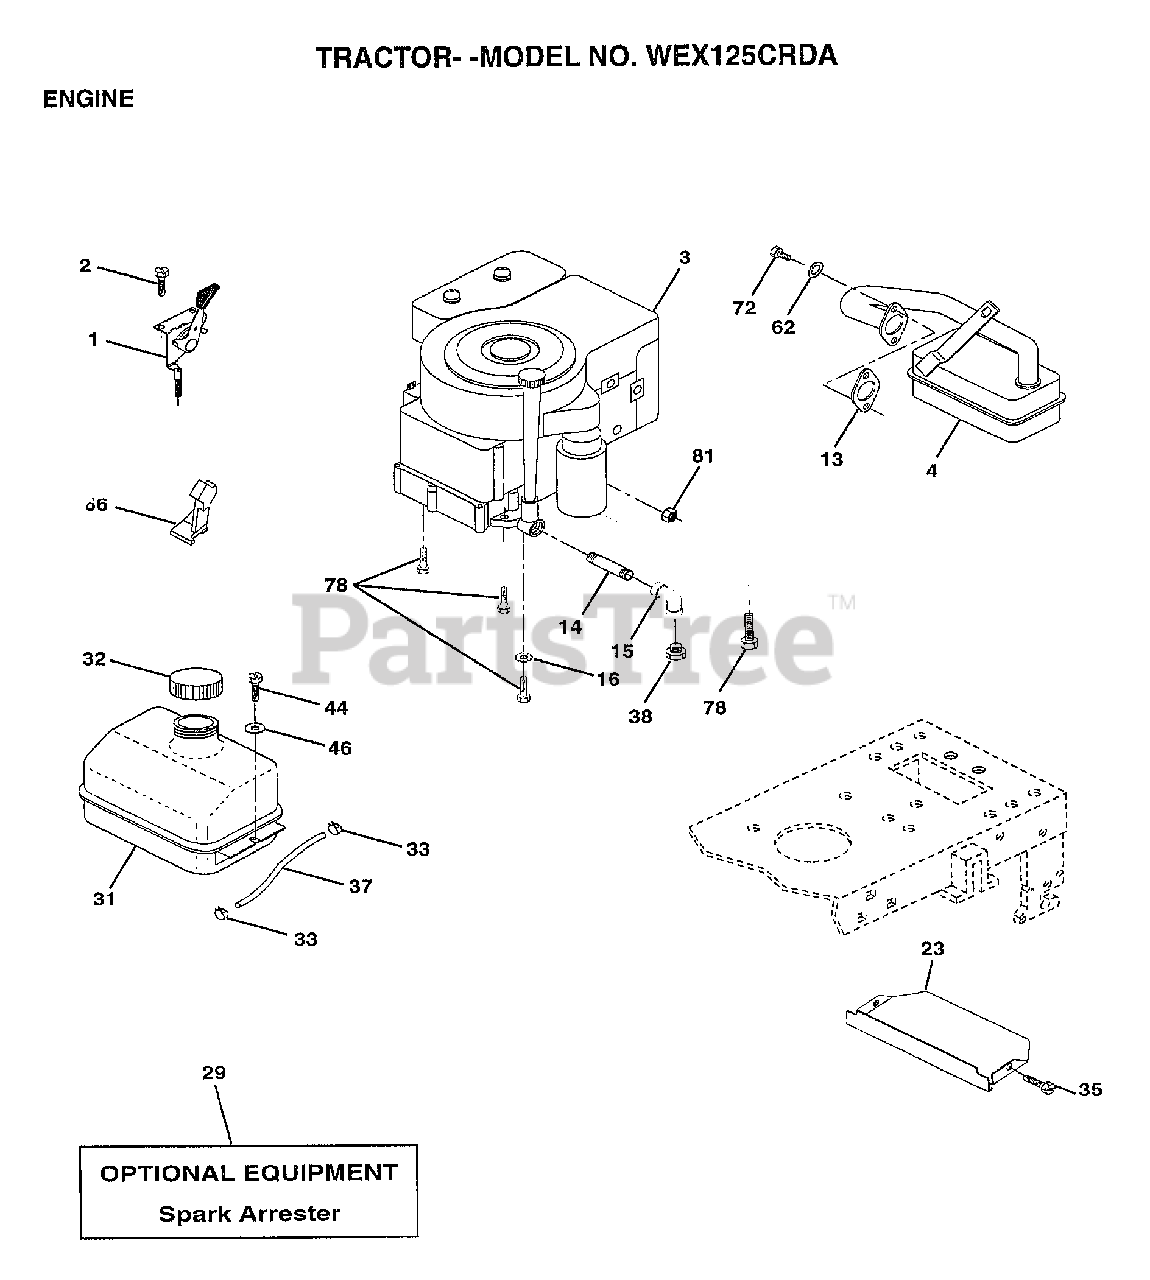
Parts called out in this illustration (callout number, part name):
1	CONTROL.THTL.23.5
2	SCREW LT
4	MUFFLER
14	PIPE NIPPLE
15	ELBOW
16	LOCKWASHER
23	SHIELD.BRN/DBR.GD
31	TANK.FUEL.LT.
32	CAP ASM FUEL
33	HOSE CLAMP
35	SCREW
37	LINE FUEL
44	SCREW HEX CRT
46	WASHER
62	LOCKWASHER
66	"STOP,DASH THROTT"
72	SCREW
78	SCREW
81	NUT
